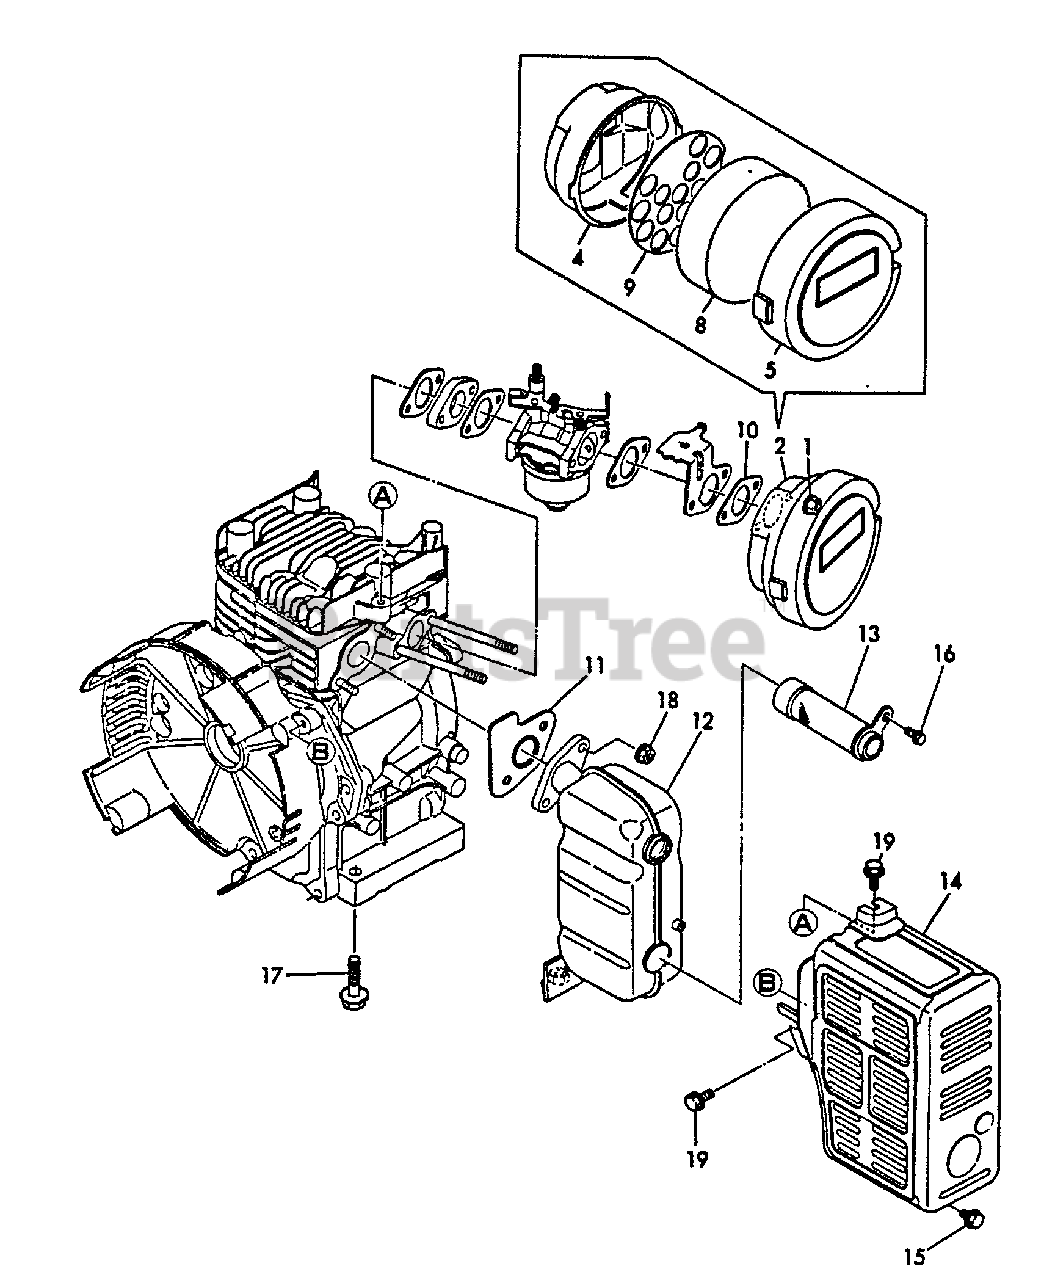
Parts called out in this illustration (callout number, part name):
1	U-NUT M6
2	CLEANER ASSY, AIR
4	CASE, AIR FILTER
5	COVER, AIR FILTER
8	FILTER, AIR
9	HOLDER, ELEMENT
10	GASKET, INTAKE
11	GASKET, EXHAUST
12	MUFFLER
13	SCREEN, SPARK ARRESTER
14	COVER, MUFFLER
15	BOLT - 6×8 -- PLATED
16	BOLT - 6×10 -- PLATED
17	BOLT - 8×30 -- PLATED
18	U-NUT M6
19	BOLT - 6×8 -- PLATED
